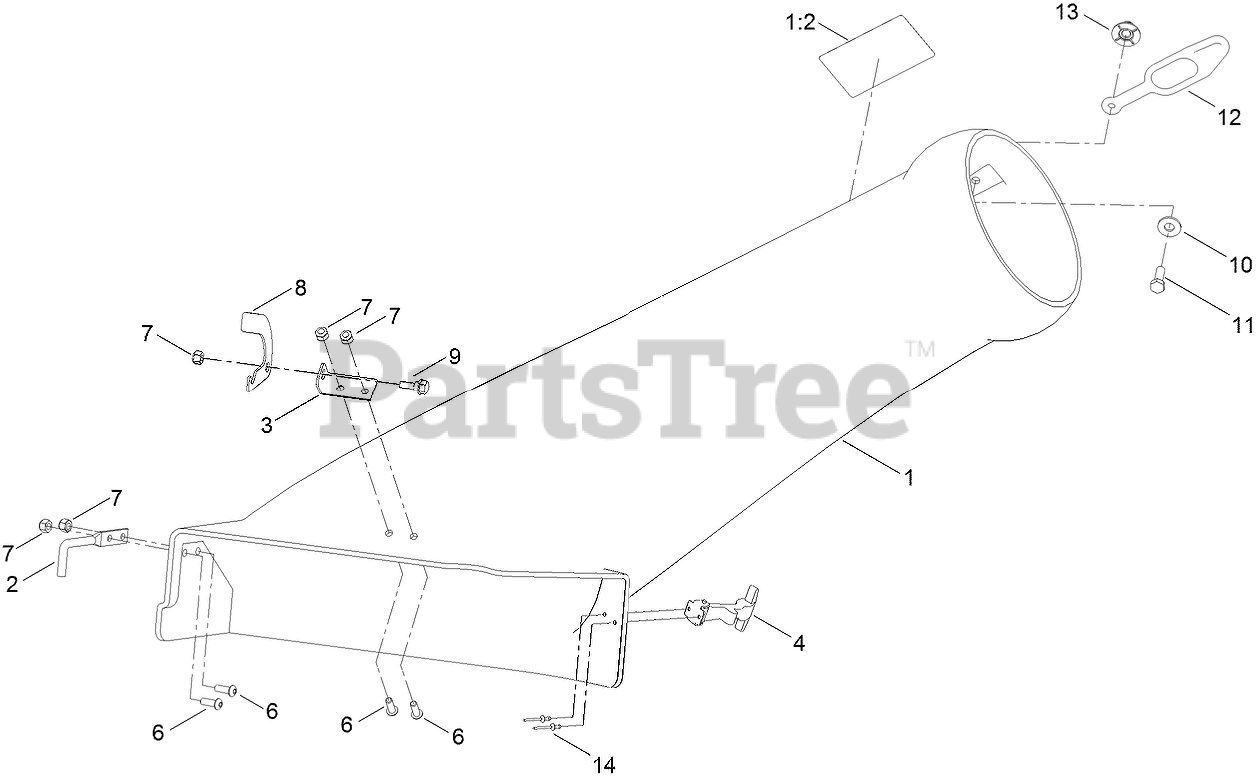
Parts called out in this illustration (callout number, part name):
1	50/54 Fab Bagger Boot
1:2	DECAL-DANGER
2	HOOK-BOOT
3	Plate-Pivot, Cz
4	HANDLE ASM
6	SCREW-HSBH
7	NUT-HEX
8	Plate-Latch
9	SCREW-SHOULDER, HHF
10	WASHER-FLAT
11	SCREW-HH
12	RETAINER-DUCT
13	NUT-IMPELLER
14	RIVET-POP
